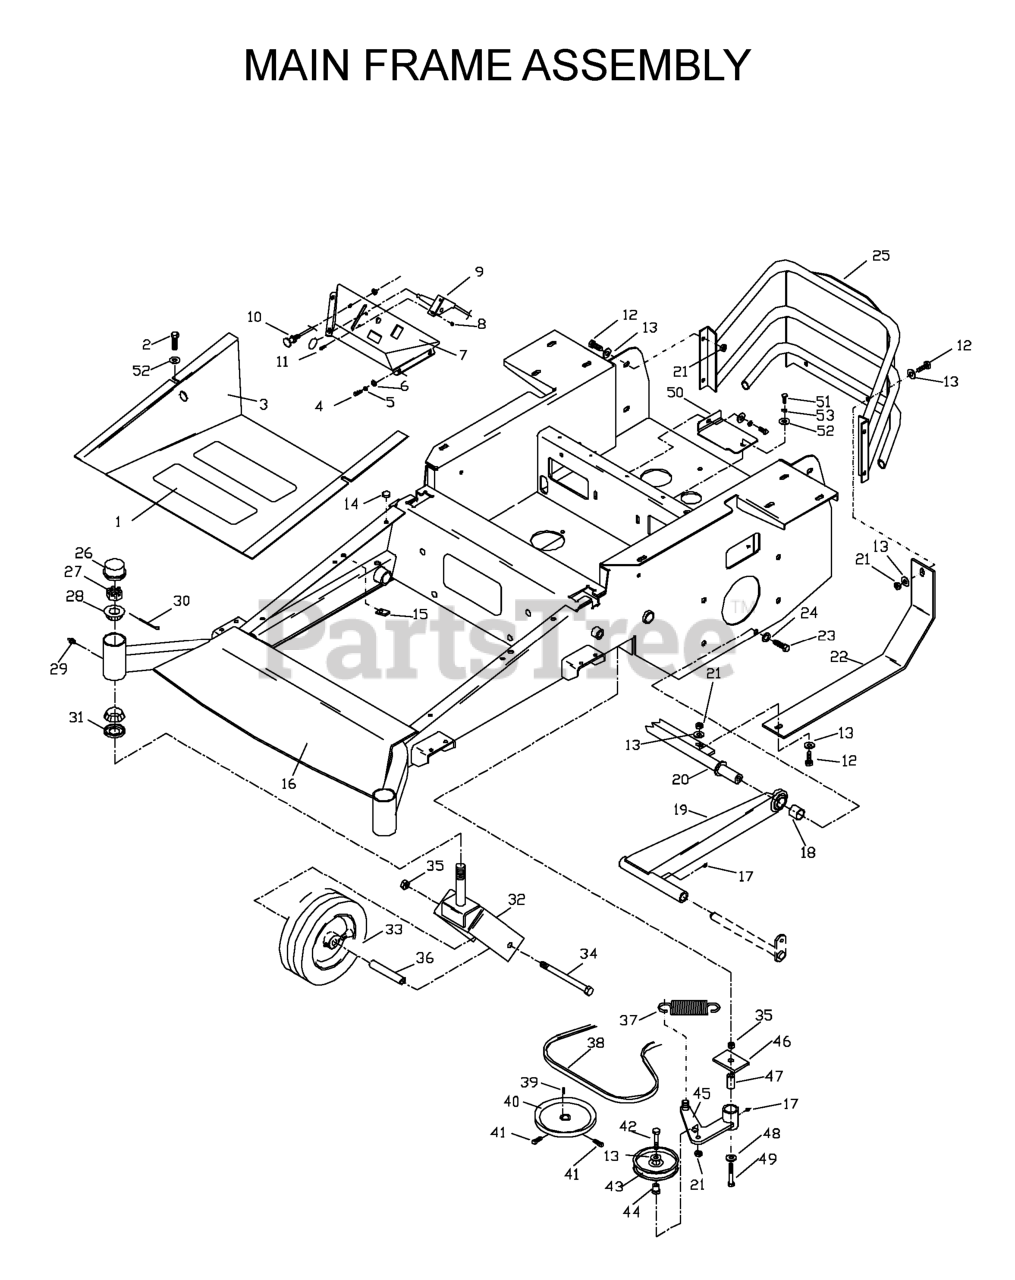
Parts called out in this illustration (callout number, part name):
1	ANTI-SKID PAD
2	HCS 5/16C X 1
4	HCS 1/4C X 3/4 HCS
5	LOCKWASHER 1/4"
6	WASHER 1/4 FLAT
7	CONSOLE W/DECALS
8	NUT 10-24 NYLOC
9	THROTTLE CONTROL W/BALL KNOB
10	CHOKE CONTROL, COMPLETE
11	HCS #10-24 X 1/2
12	HCS 3/8-16X1.GRD.5.ZD
13	WASHER 3/8 FLAT
14	GROMMET, BUMPER
15	U-CLIP 5/16-18 NUT RETAINER
17	ZERK
18	SPACER, STRUT
20	CROSS SHAFT WLDMT
21	NUT 3/8C CENTERBLOCK
23	HCS 7/16-14 X 1 GR 5 ZD
24	WASHER 7/16 LOCK
25	EURO ENGINE GUARD
26	GREASE CAP
27	NUT 1"C HEX SLOTTED
28	BEARING W/CUP
30	COTTER PIN 1/8 X 2
32	CASTER YOKE ORANGE
33	TIRE.ASSEM.13X5-6.SMOOTH.SILVE
34	SCREW 1/2C X 7 1/2 HEX CAP
35	NUT 1/2-13 HEX NYLOC ZD
36	SPACER, CASTER
38	PUMP BELT
39	KEY 5 MM SQ X 25 MM
41	SCREW 5/16C X 5/8 SQ HEAD
42	HCS 3/8-16 X 1 3/4 GR5
43	IDLER PULLEY
44	BUSHING, IDLER FLANGE
45	IDLER ARM WLDT
47	PIVOT BUSHING
48	WASHER 1/2 FLAT
49	HCS 1/2C X 3 1/4
50	IDLER COVER
51	HCS 5/16C X 3/4
52	WASHER 5/16 FLAT
53	WASHER.LOCK.HVY.HLCL.SPR.5/16
539102484	BEARING RETAINER
539102485	ROLLER BEARING
539102546	TIRE - FRONT
539104573	RIM
539912234	VALVE STEM TR-412
539976997	ZERK 1/8 NPT
